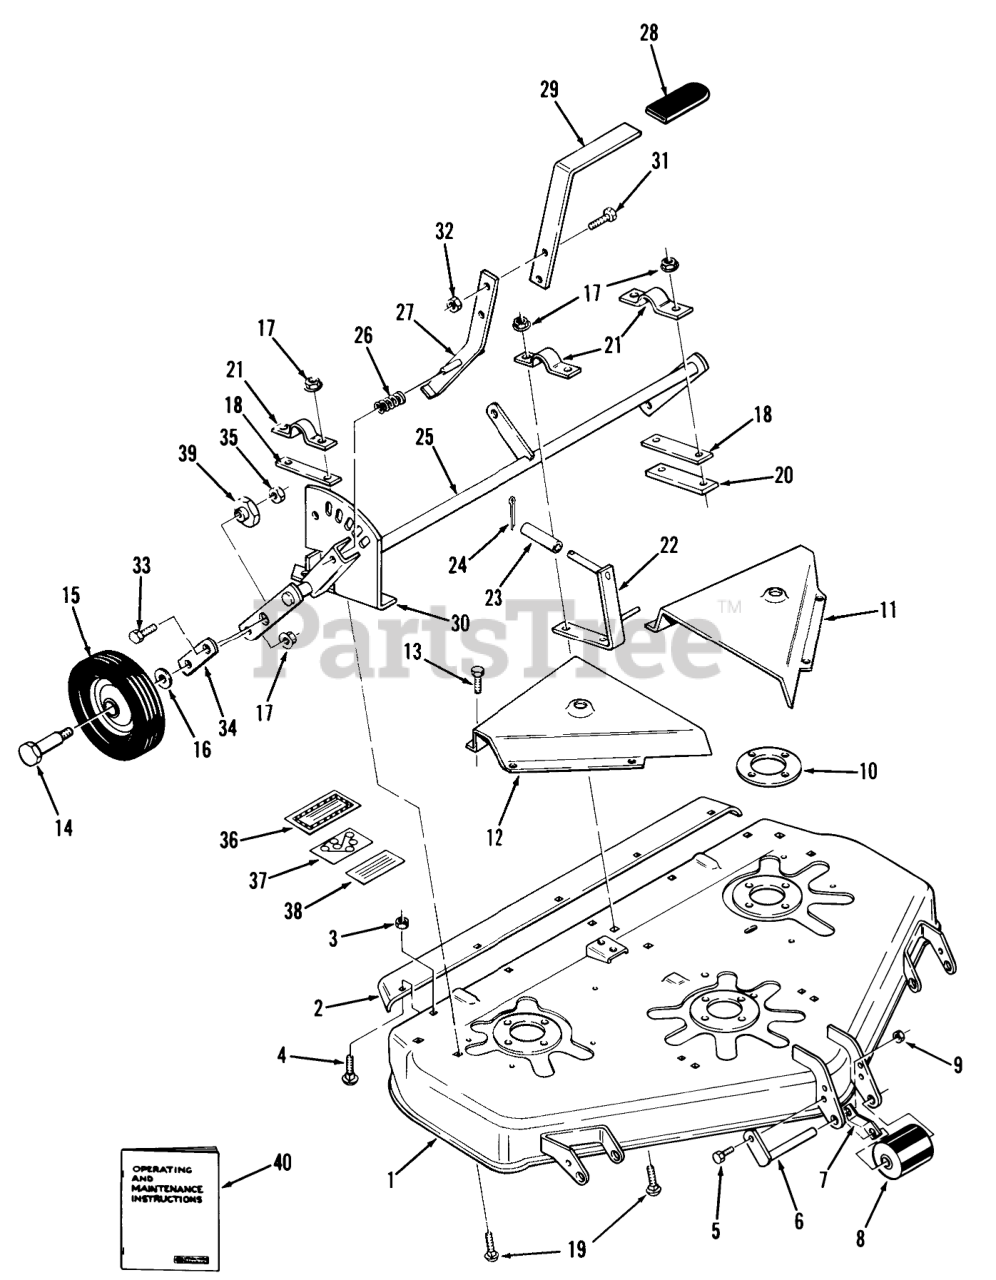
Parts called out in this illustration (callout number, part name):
1	Mower Deck Assembly
2	Rear Chute Extension
3	Nut
4	CARRIAGE BOLT -4
5	H H C S
6	Roller Shaft
7	SPRING ROLLER STOP
8	Roller
9	Nut
10	PLATE-SPINDLE
11	Belt Cover LH
12	Belt Cover RH
13	Bolt
14	BOLT-SHOULDER
15	Wheel 6 x 1.75
16	WASHER
17	LOCKNUT-FLANGE
18	Strap 1/16
19	Bolt
20	Strap
21	CLAMP
22	Bracket Guide
23	SPACER
25	Gage Wheel Support
26	SPRING-COMPRESSION
27	Lever
29	HANDLE-EXTENSION R
30	Quadrant
31	Bolt
32	Nut
33	Bolt
34	Wheel Plate
35	Nut
36	Caution Decal
37	DECAL-HEIGHT BELT
38	Decal-Caution
39	STEERING ARM
40	OperatingandMaintenanceInstructions
